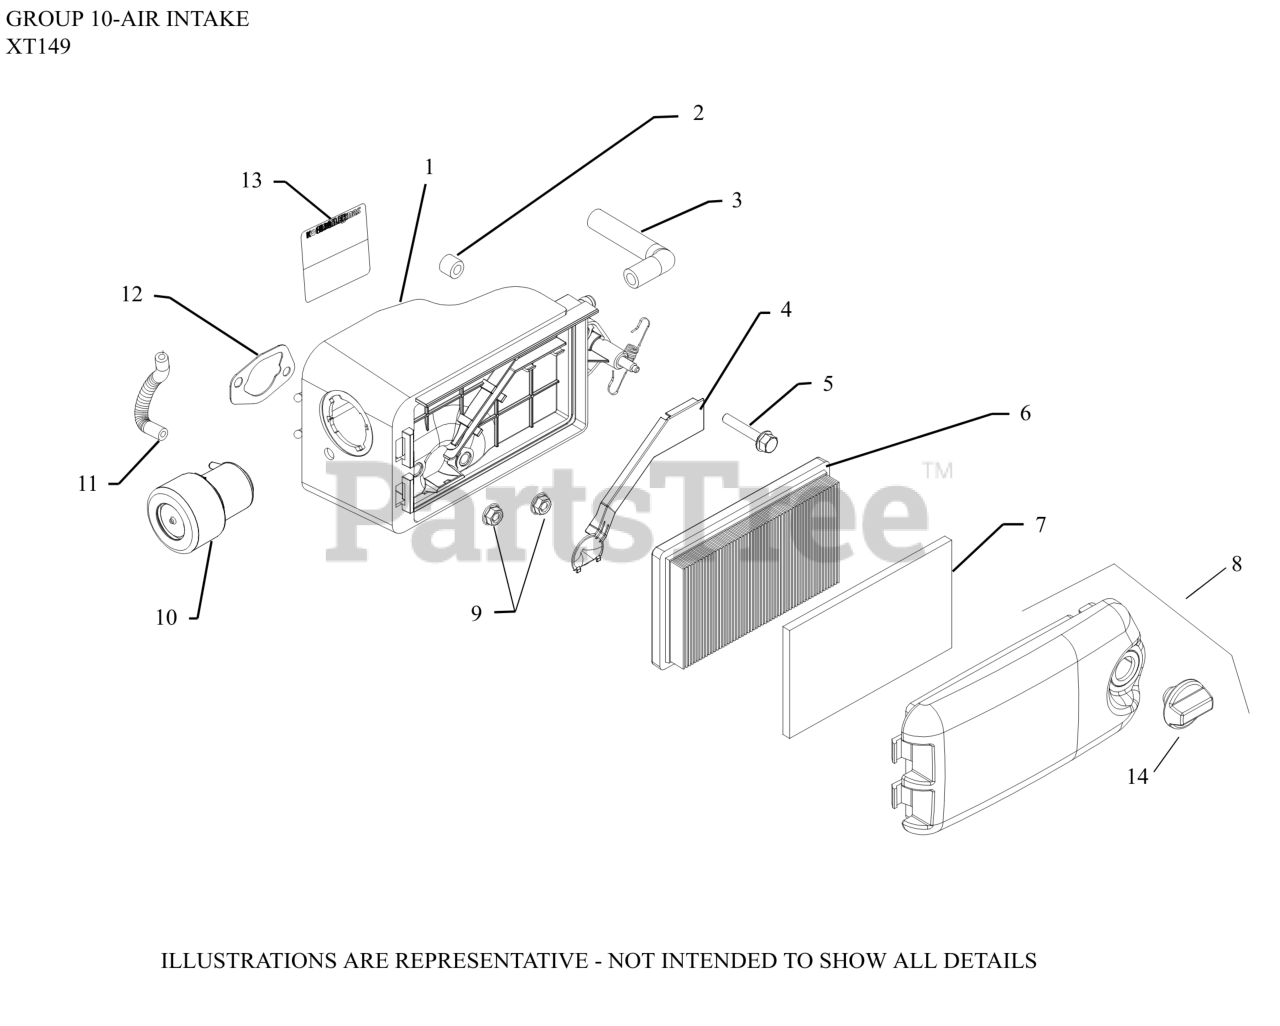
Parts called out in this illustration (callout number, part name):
1	AIR CLEANER BASE-USE 14 094 23-S
3	HOSE, BREATHER
4	COVER, A/C BASE (BREATHER GAS)
6	ELEMENT, AIR CLEANER-(#1408319S)
7	ELEMENT, CARBON PRE-FILTER
8	COVER, AIR CLEANER
12	KIT, INTAKE GASKET
14	KNOB-USE 14 341 07-S
NI	GASKET, AIR CLEANER BASE
